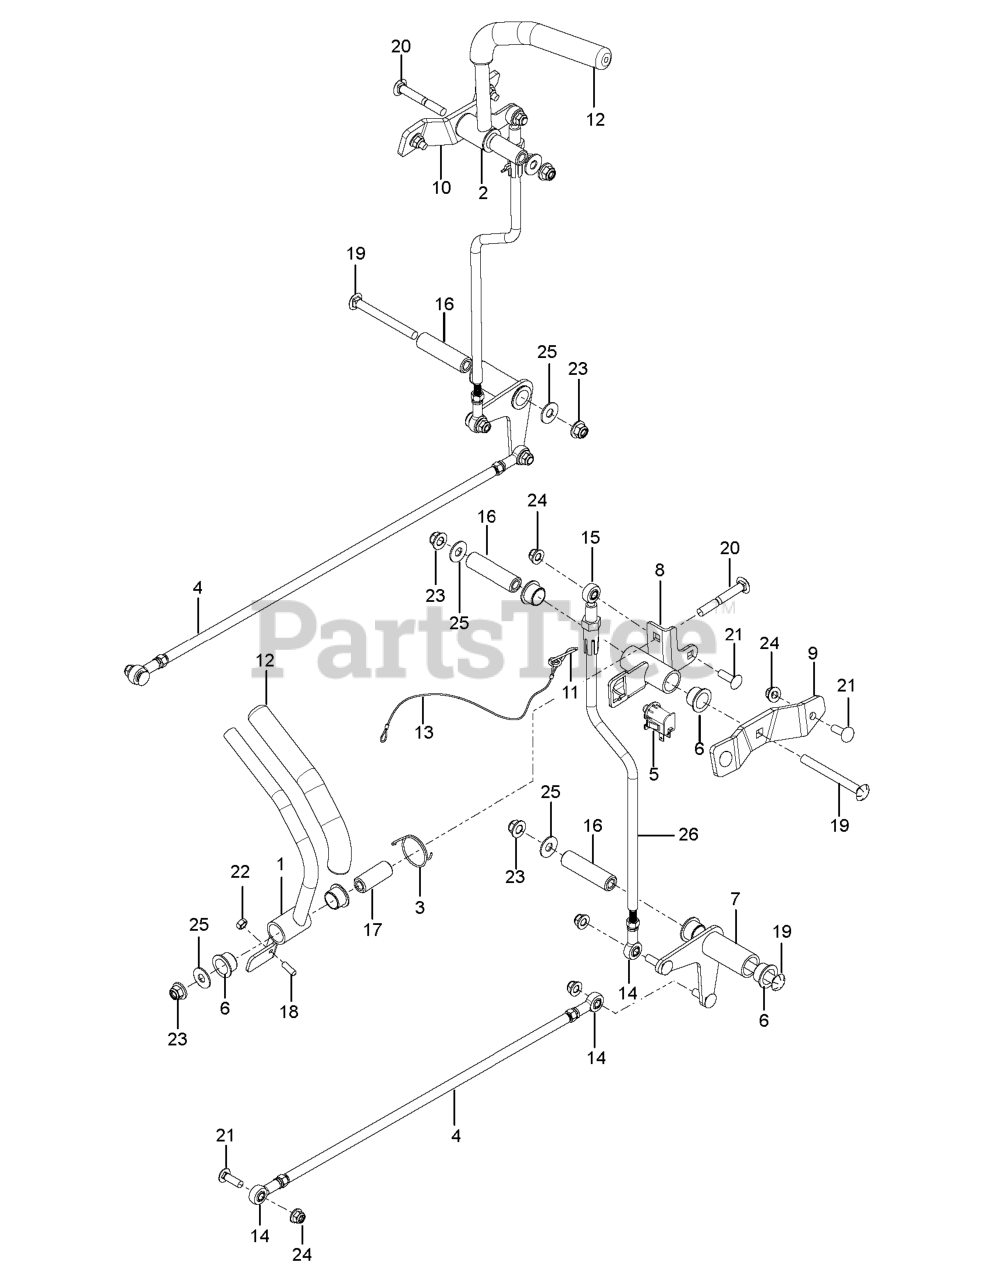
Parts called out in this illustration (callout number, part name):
1	LEVER ASSY WELDMENT; OPS E-DIP
2	HANDLE ASSY HANDLE WELDMENT, R
3	SPRING TORSION; OPS
4	LINKAGE CONTROL LINKAGE ASSY;
5	SWITCH.SNAPMOUNT.NC
6	BEARING, FLANGE
7	BELLCRANK WELDMENT; STAND ON C
8	BELLCRANK WELDMENT; CONTROLS;
9	BRACKET LH PIVOT; STAND ON E-D
10	BRACKET RH PIVOT; STAND ON E-D
11	CLIP.RETAINER.CONTROLS
12	GRIP 1/2 DIAM; .215 THICK; 8.5
14	ROD END FEMALE RH THREAD
15	CONTROL ROD COUPLER KIT
15	ROD.END.MALE.LH.THREAD
16	SPACER BELLCRANK PIVOT LONG
17	SPACER BELLCRANK PIVOT SHORT
18	SCREW ASME B18.3, HEXAGON SOCK
21	RHSSNB 5/16C X 1.0
22	NUT
23	NUT 3/8-16 HEX FLG NYLOC ZD
24	5/16-18 NYLOC FLANGE NUT
25	WASHER
26	Controls
